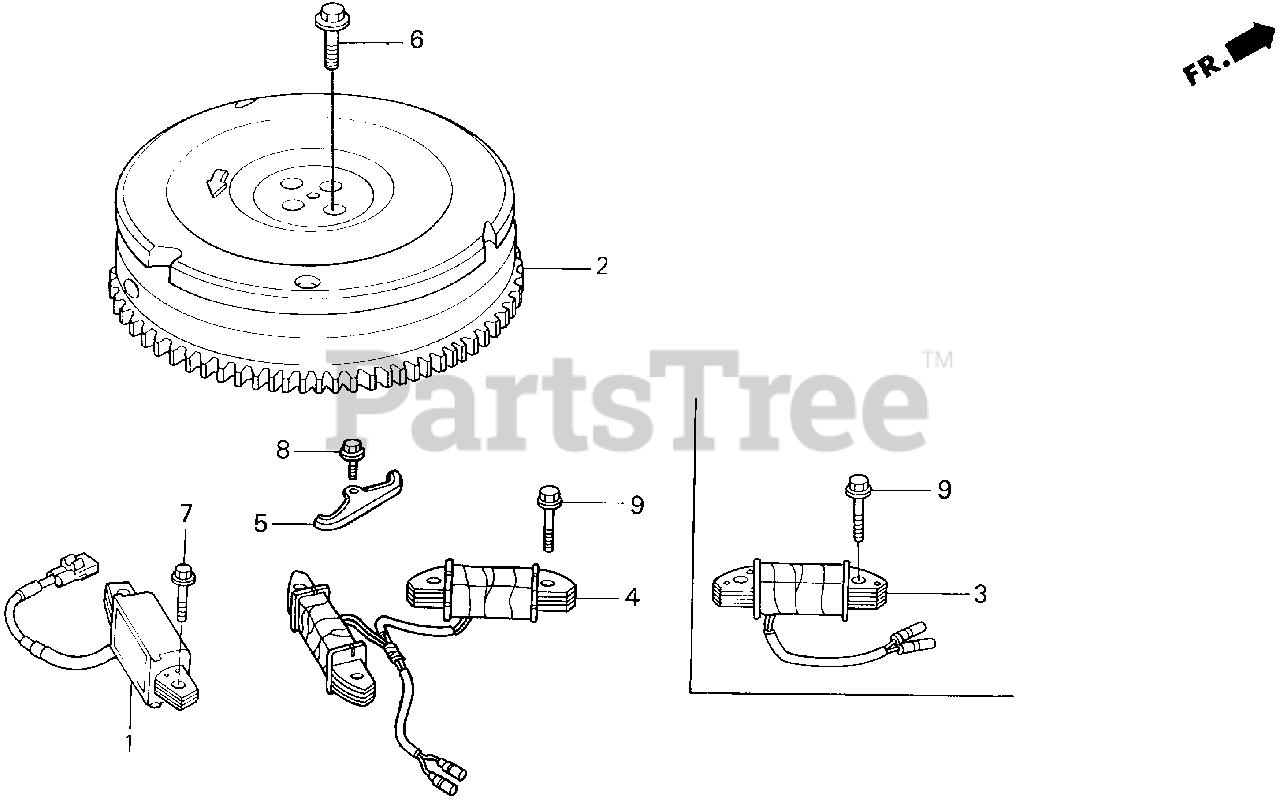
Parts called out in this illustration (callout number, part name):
1	COIL ASSY., EXCITER
2	FLYWHEEL *TBLACK* (BLACK)
4	COIL ASSY., CHARGE (12V-10A)
4	COIL ASSY., CHARGE (12V/10A)
5	HOLDER, WIRE (B)
6	BOLT, FLANGE (10X25)
7	BOLT, FLANGE (6X25)
8	BOLT, FLANGE (6X12)
9	BOLT, FLANGE (6X32)
